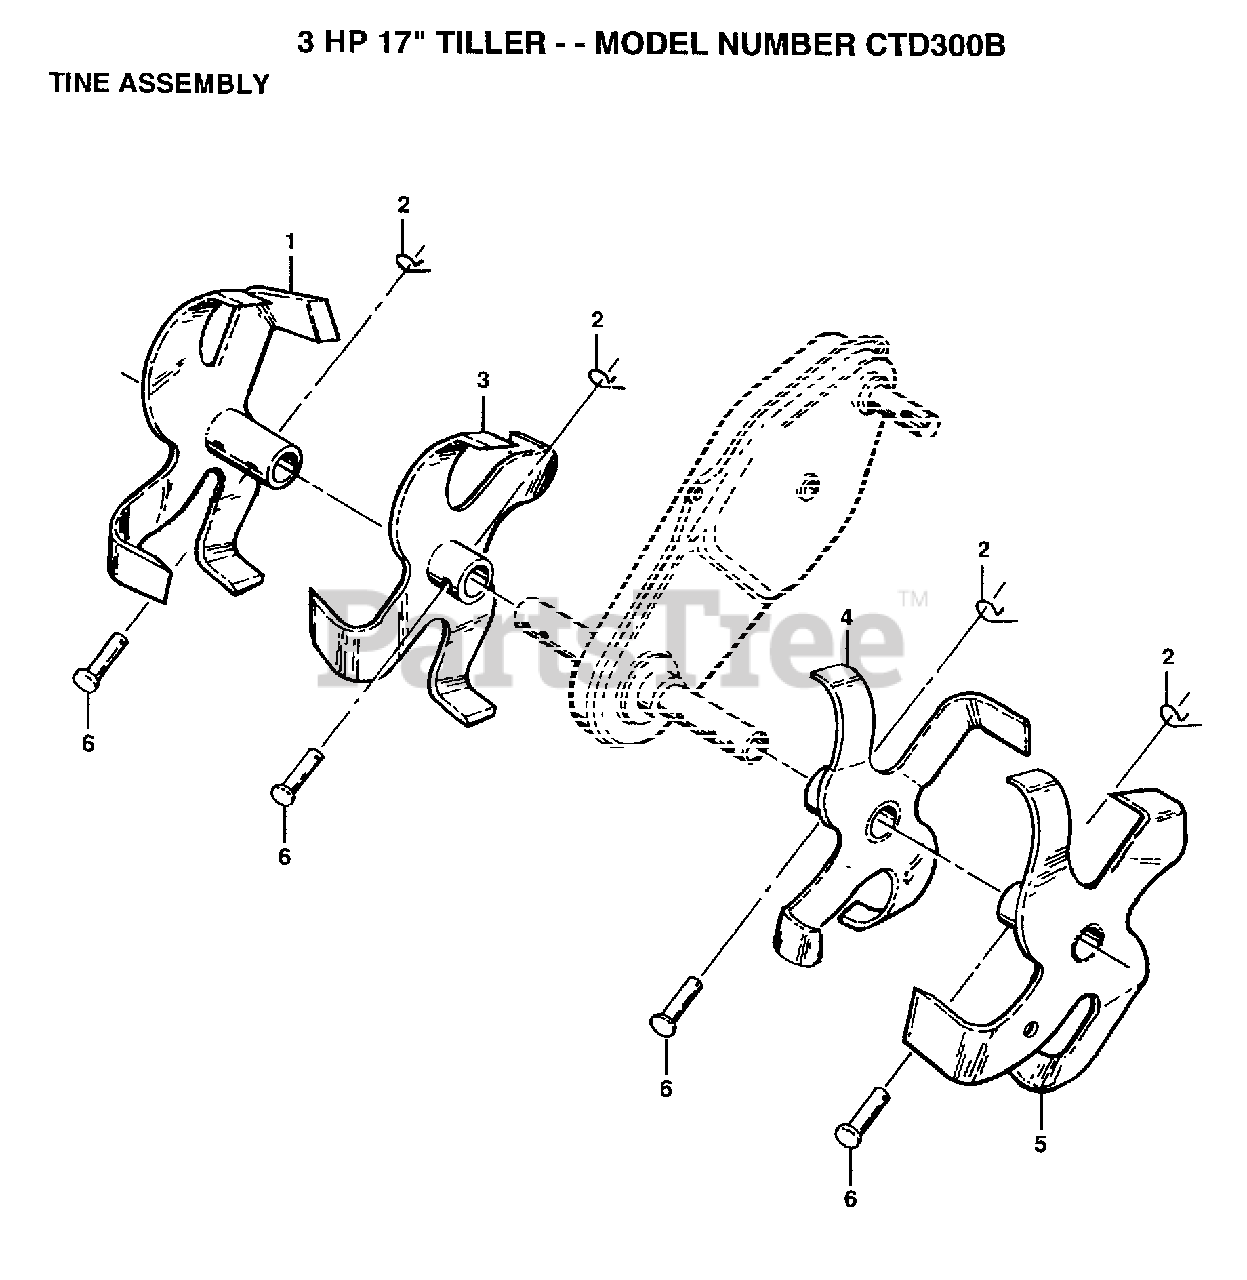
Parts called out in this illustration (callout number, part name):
2	NUT.HEX.5/16-18
3	LOCKWASHER
4	WASHER
5	SPRING.RETAINER
6	BOLT
7	STAKE.SUPT.TILLER
8	STAKE.DEPTH.PNT
9	NUT
10	DRILLED RIVET RT
12	BOLT
13	STAKE SPRING CT
14	BOLT SHOULDER
16	WASHER
19	NUT
